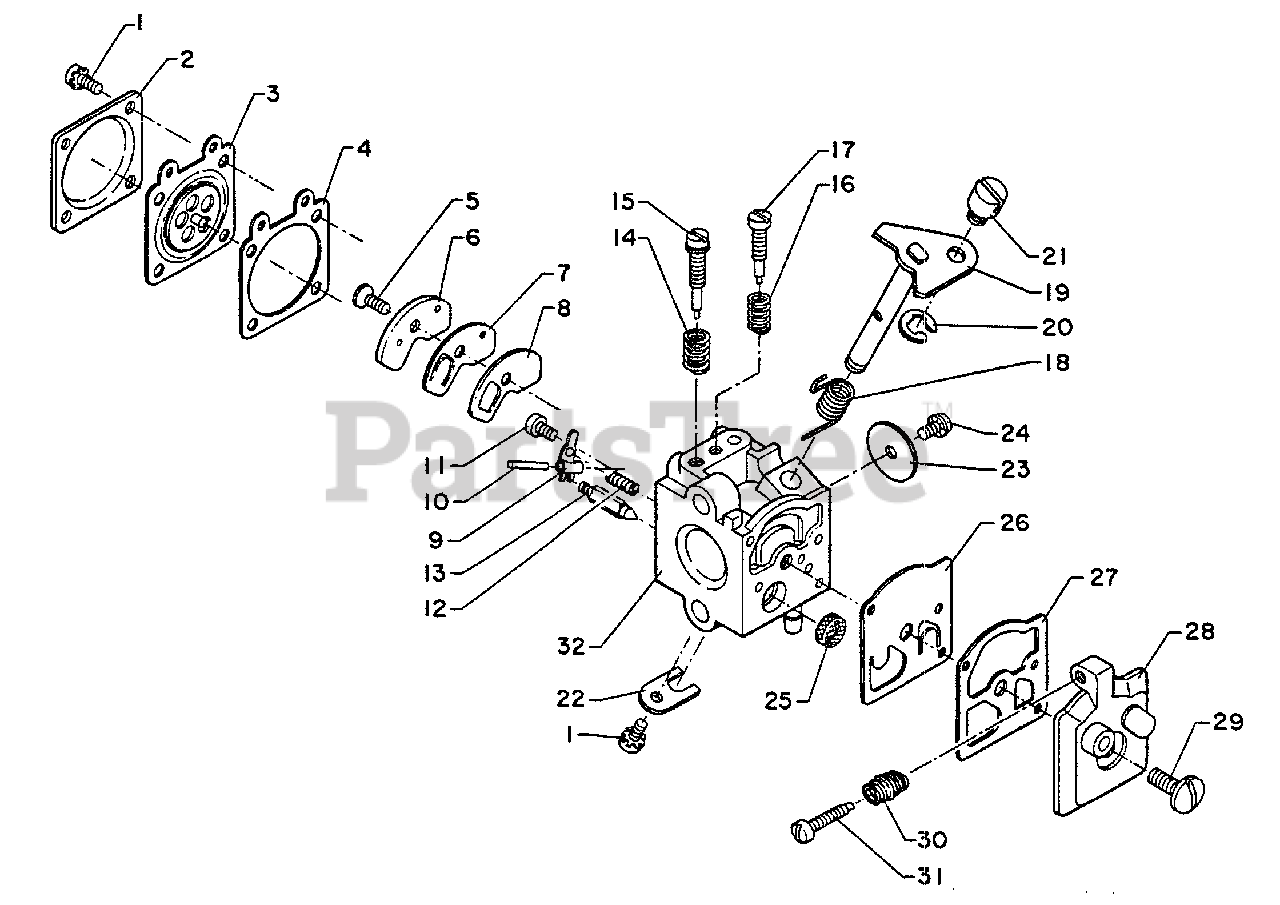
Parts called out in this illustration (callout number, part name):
1	SCREW
2	COVER, METERING
3	DIAPHRAGM, METERING
4	GASKET, METERING
5	SCREW, CIRCUIT PLATE
6	PLATE, CIRCUIT
7	DIAPHRAGM, CIRCUIT PLATE
8	GASKET, CIRCUIT PLATE
9	LEVER, METERING
10	PIN, METERING LEVER
11	SCREW, METERING LEVER PIN
12	SPRING, METERING LEVER
13	VALVE, INLET NEEDLE
14	SPRING, HIGH SPEED NEEDLE
15	NEEDLE - HIGH SPEED
16	SPRING, LOW SPEED NEEDLE
17	NEEDLE - LOW SPEED
18	SPRING, THROTTLE RETURN
19	SHAFT, THROTTLE
20	RING, RETAINING
22	CLIP, THROTTLE SHAFT
23	VALVE, THROTTLE
25	STRAINER
26	DIAPHRAGM, PUMP
27	GASKET, PUMP
28	COVER, PUMP
29	SCREW, PUMP COVER
30	SPRING, IDLE ADJUST
31	SCREW, IDLE ADJUST
32	BODY, CARBURETOR
